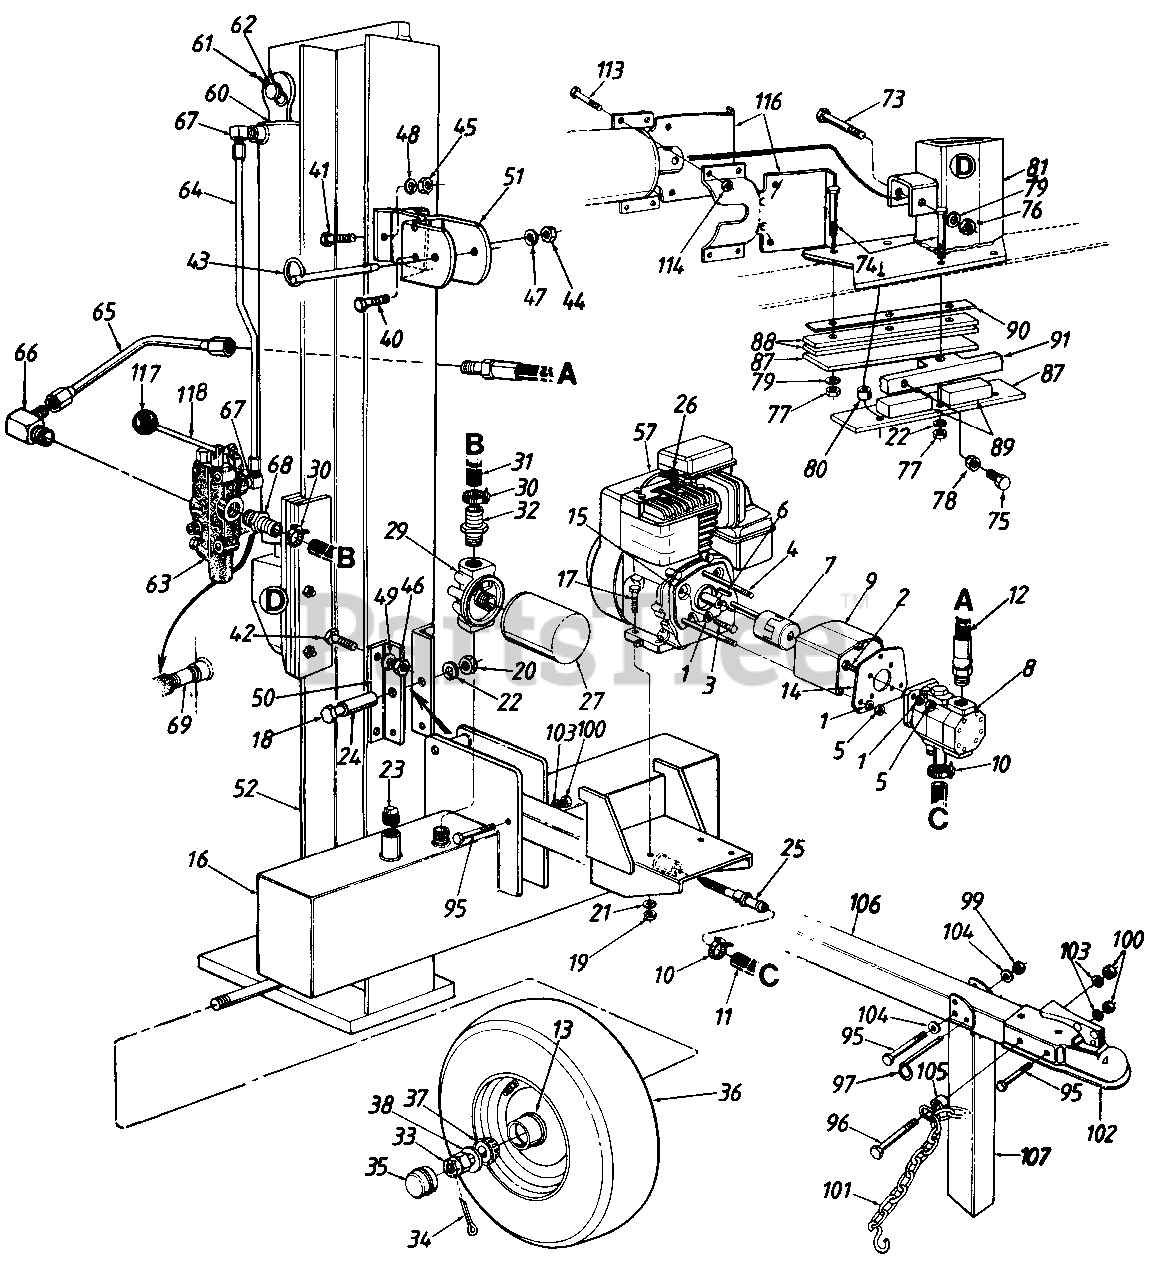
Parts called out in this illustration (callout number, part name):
1	L-Wash. 5/16" I.D.
2	Hex Bolt 5/16-24 x 1" Lg.
3	Hex Bolt 5/16-24 x .62" Lg.
4	Hex Bolt 5/16-24 x 4" Lg.
5	Hex Nut 5/16-24 Thd.
6	Sq.-Key 3/16 x .75
7	Flexible Coupling
8	Two Volume Pump
9	Coupling Shield
10	Hose Clamp 5/8"
11	Suction Hose 1" I.D.
12	High Pressure Hydraulic Hose 56"
13	Bearing Seal
16	Tank Ass'y. Complete
17	Hex Bolt 5/16-24 x 1.75" Lg.
18	Hex Bolt 1/2-20 x 4" Lg.-Grade 5
19	Hex Nut 5/16-24 Thd.
20	Nut 1/2 BL NF-20
21	L-Wash. 5/16" I.D.
22	L-Wash. 1/2" I.D.
23	Pipe Plug
24	Pivot Bushing .75" O.D.
25	Strainer Ass'y.
26	Spark Plug Cover
27	Filter Element
29	Filter Head
30	Adjustable Hose Clamp
31	Return Hose 3/4" I.D. x 30" Lg.
32	3h" Dia. Hose Barb
33	Slotted Nut 3/4-16 Thd.
34	Cotter Pin 5/32n
35	Hub Cap
37	Roller Bearing w/Race
38	Fl-Wash. .760" I.D. x 1.5" O.D.
40	Hex Bolt 5/16-24 x 1 " Lg.
41	Hex Bolt 3/8-16 x 1" Lg.-Grade 5
42	Hex Bolt 7/16-20 x 1.25" Lg.- Grade 5
43	Quick Release Pin
44	Hex Nut 5/16-24 Thd.
45	Hex Nut 3/8-16 Thd.-Grade 5
46	Hex Patch L-Nut 7/16-20 Thd.
47	L-Wash. 5/16n I.D.
48	L-Wash. 3/8" I.D.
49	L-Wash. 7/16" I.D.
50	Beam Mtg. Plate
51	Beam Latch Bracket
52	Vertical Beam Ass'y.
57	Engine-Briggs & Stratton 5 H.P. No. 130202-3116-01
60	Hydraulic Cylinder 4" Dia.
61	External Cotter Pin
62	Cylinder Mtg. Pin
63	Control Valve-3200 PSI
64	Metal Pressure Tube 1/2" O.D.
65	Pressure Tube 1/2" Dia.
66	90ø Solid Male Adapter
67	90ø Solid Male Adapter
68	3/4n Dia. Hose Barb
69	Pipe Nipple 1/2 NPT
73	Hex Bolt 1/2-20 x 3" Lg. (Grade 8)
74	Hex Bolt 1/2-20 x 2.75" Lg.- Grade 8
75	Hex Bolt 3/8-24 x 1.5" Lg.
76	Hex L-Nut 1/2-20 Thd.
77	Nut 1/2 BL NF-20 Thd.
78	Hex Jam Nut 3/8-24 Thd.-Grade 5
79	L-Wash. 1/2" I.D.
80	Spacer 818n I.D. x 3/4" O.D.
95	Hex Bolt 3/8-16 x 3" Lg.-Grade 8
96	Hex Bolt 3/8-16 x 3.25" Lg.- Grade 8
97	Quick Release Pin
99	Hex L-Nut 3/8-16 Thd.
100	Hex Nut 3/8-16 Thd.
101	Chain-Tow Hitch
102	Hitch Coupler
103	L-Wash. 3/8
104	Fl-Wash. .406n I.D. x .75
105	Spacer .38" I.D. x .625" O.D.
106	Tongue Tube
107	Jack Stand Ass'y.
113	Hex Bolt 3/8-16 x 2" Lg.-Grade 5
114	Hex Insert L-Nut 3/8-16 Thd.
118	Control Handle
